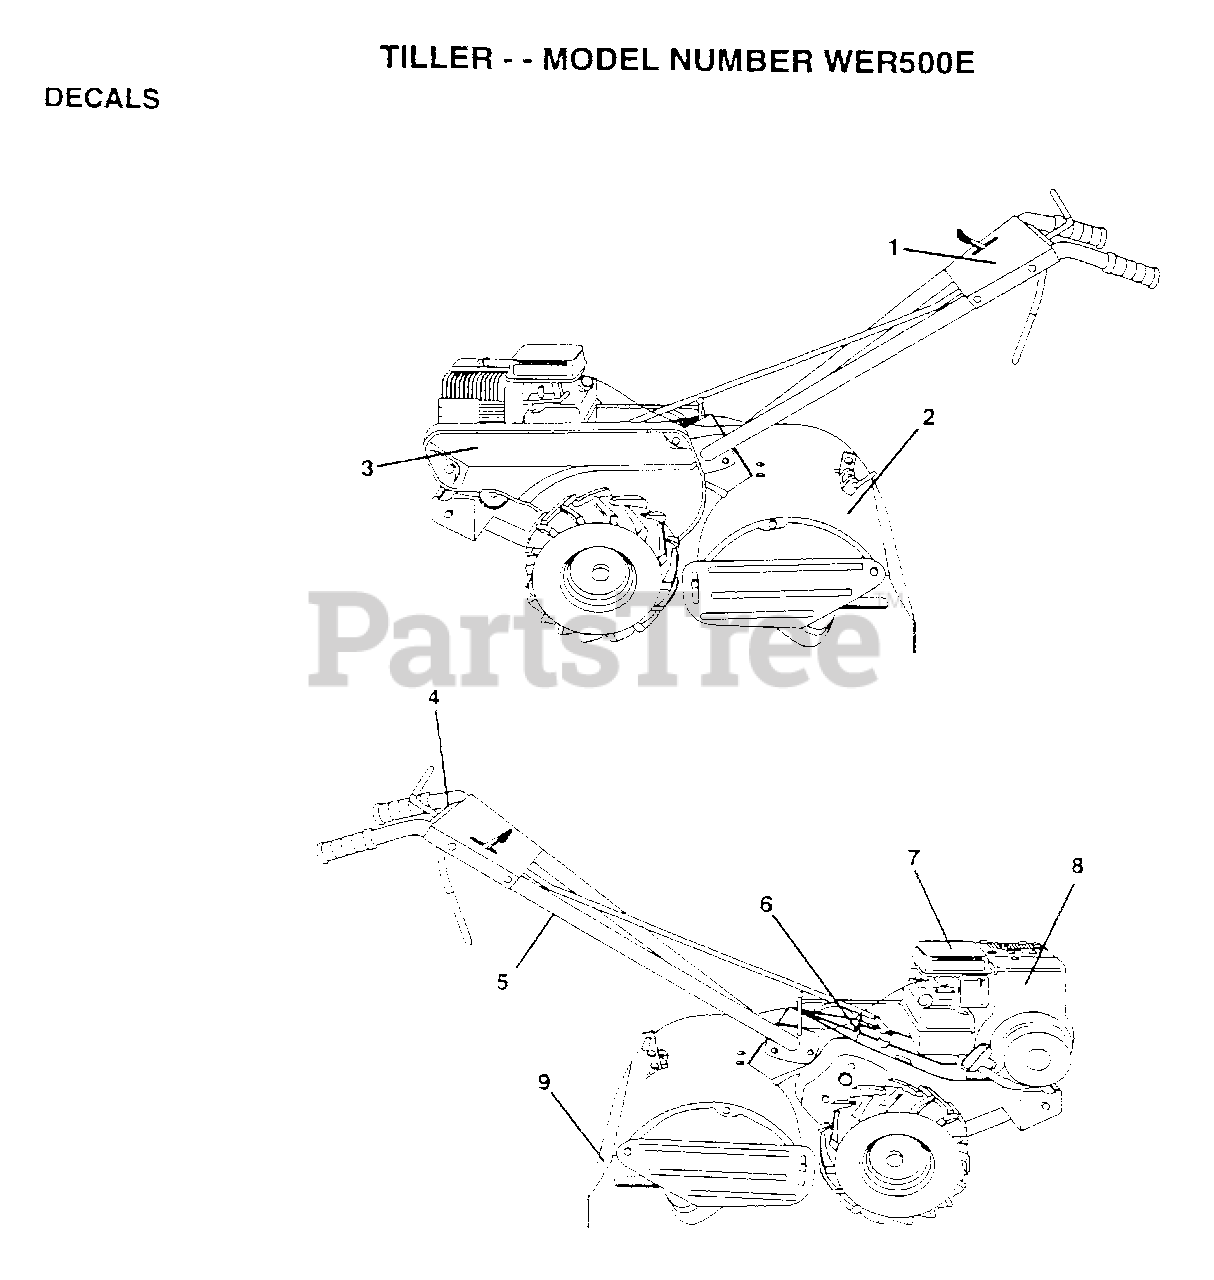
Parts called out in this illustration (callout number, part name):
1	DECAL LOGO 17 5HP
2	DECAL SHIELD TINE
3	DECAL BELT GUARD
5	DECAL TI
7	DECAL TI
8	DECAL, BRIGGS & STRATTON
